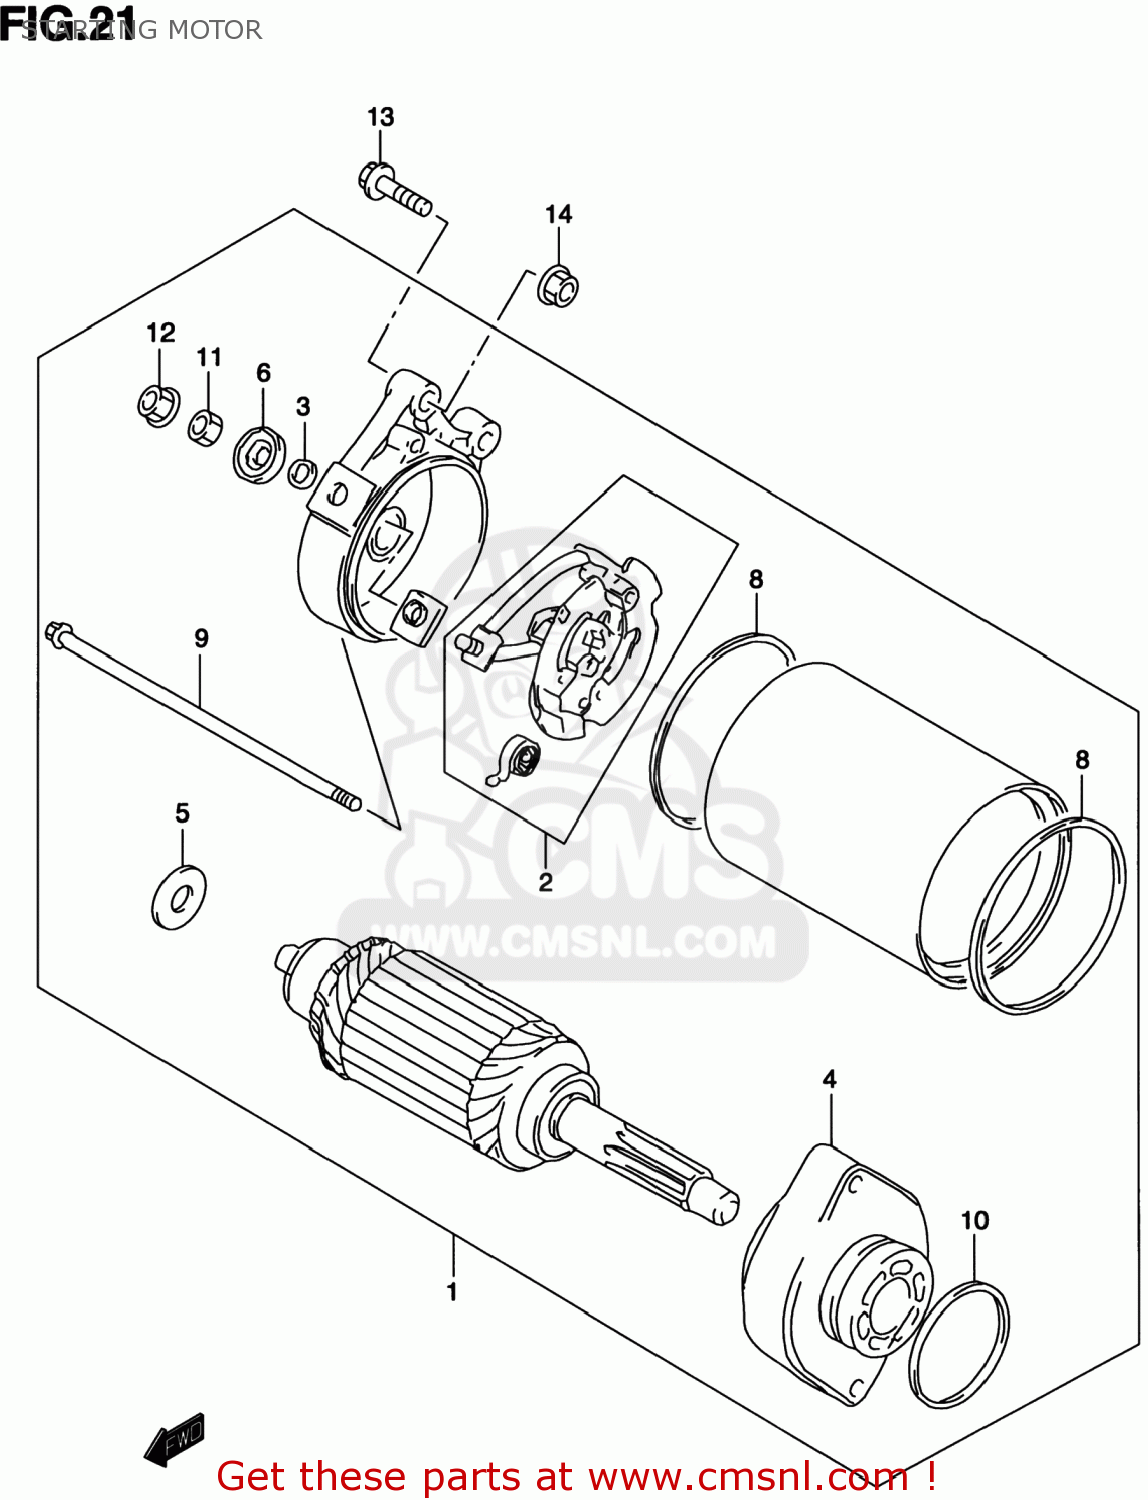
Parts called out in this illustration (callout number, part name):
1	MOTOR ASSY,STARTING
2	HOLDER SET,BRUSH
3	O RING
4	BRACKET SET
5	SHIM SET,STARTING MOTOR
6	BUSHING
7	BUSHING
8	O RING
9	BOLT
10	O-RING (D:2 ID:35)
11	NUT
12	NUT
13	BOLT
14	NUT
